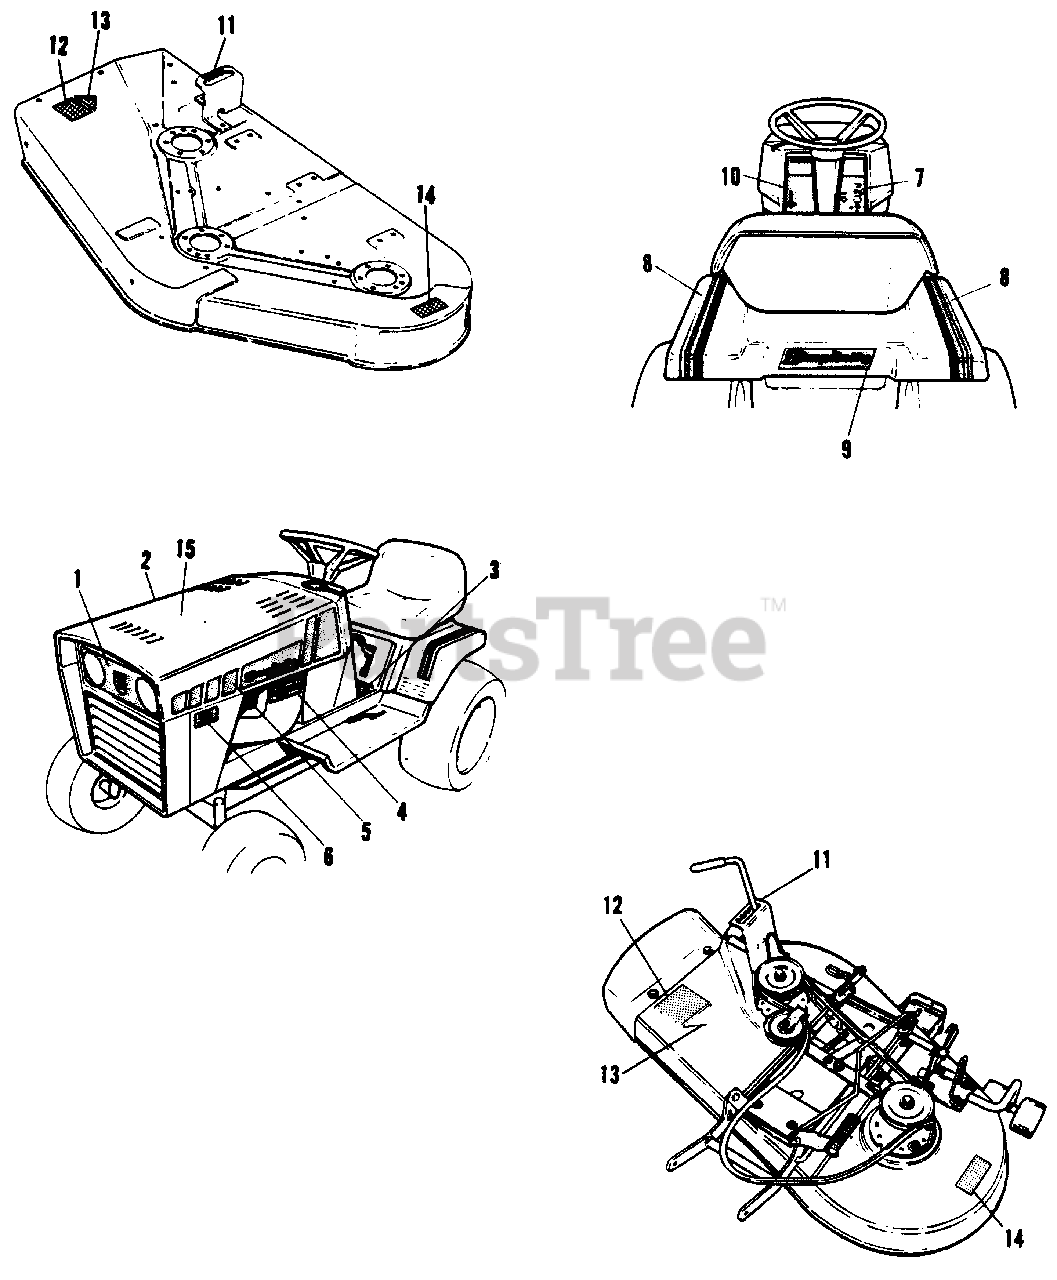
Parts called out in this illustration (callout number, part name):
1	DECAL, Grille
2	DECAL, Hood, R.H.
3	DECAL, Shift
4	DECAL, Engine
5	DECAL, Hood, L.H.
6	DECAL, 5216 Hydro
7	DECAL, Dash, R.H.
8	DECAL, Seat Deck
9	DECAL, Simplicity
10	DECAL, Dash, L.H.
11	DECAL, Mower Height
12	DECAL, Warning
13	DECAL, OPEI
14	DECAL, Danger
15	DECAL, Drive Belts (Inside Hood)
